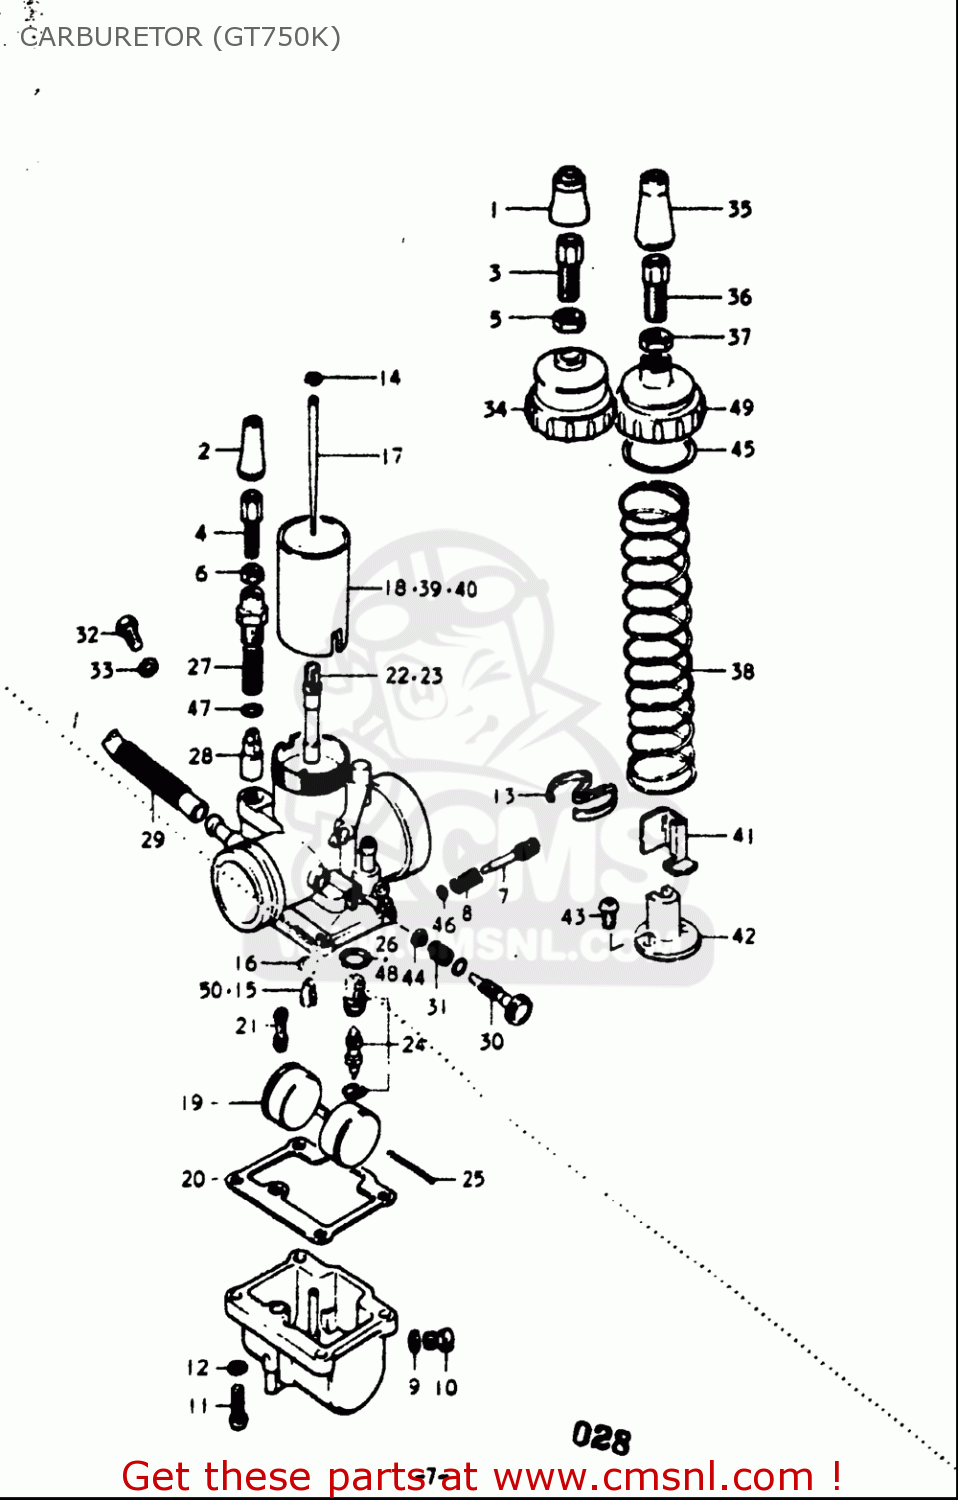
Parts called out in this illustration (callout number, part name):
2	CAP
4	ADJUSTER,CABLE
6	NUT
7	SCREW,PILOT AIR
8	SPRING
9	GASKET,DRAIN,PLUG (NAS)
10	PLUG
11	SCREW 4X16
12	WASHER,LOCK
14	CLIP
15	JET,MAIN(102.5)
16	WASHER
19	FLOAT
20	GASKET,FLOAT CAHMBER (NAS)
21	JET,PILOT(30)
24	VALVE ASSY,NEEDLE
25	PIN,FLOAT
26	GASKET,MAIN JET HOLDER (NAS)
27	SPRING
28	PLUNGER,STARTER
31	SPRING,THROTTLE SCREW
32	BOLT
33	GASKET,THRO VALVE INSPECTION (NAS)
35	CAP
36	ADJUSTER,CABLE
37	NUT
42	CONNECTOR
43	SCREW
44	COVER
46	O RING
48	GASKET,MAIN JET HOLDER (NAS)
50	JET,MAIN(105)
